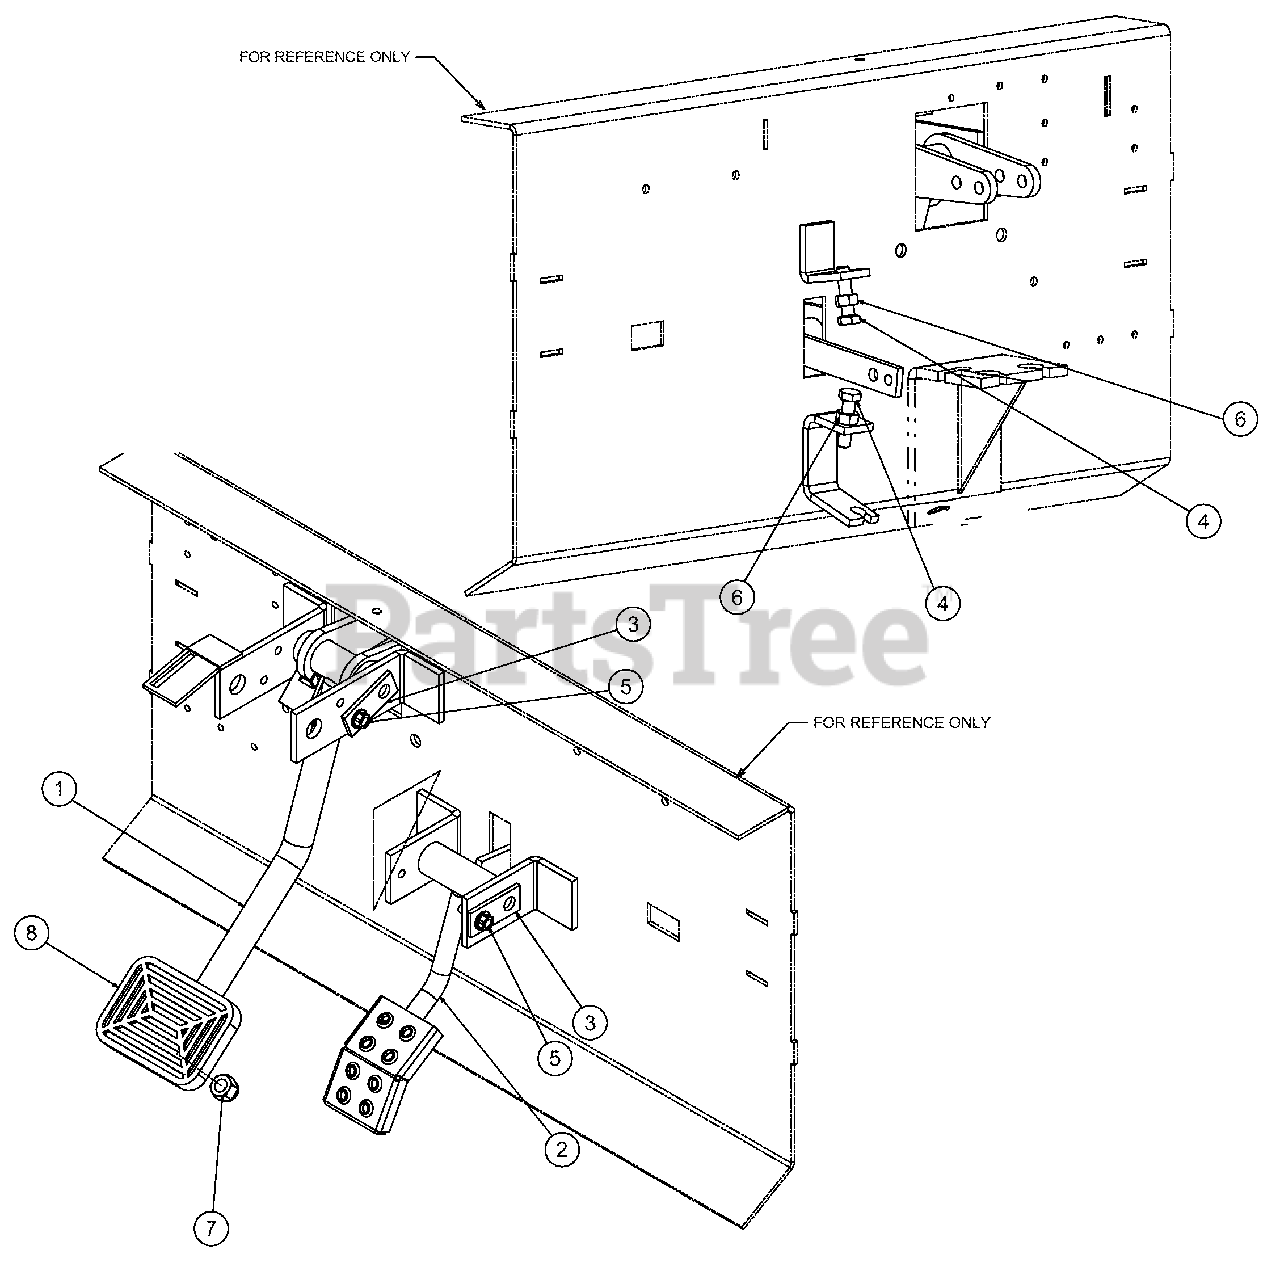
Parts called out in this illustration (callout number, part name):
3	Shaft Assembly, Pedal Pivot
4	Hex Screw, 5/16-18, 1.25, Gr5
5	Screw, Self-tapping, 1/4-20 x .75
6	Nut, Hex Lock, 5/16-18, Gr5
7	Lock Nut, Nylon, 3/8-24
8	Pad, Pedal Brake
